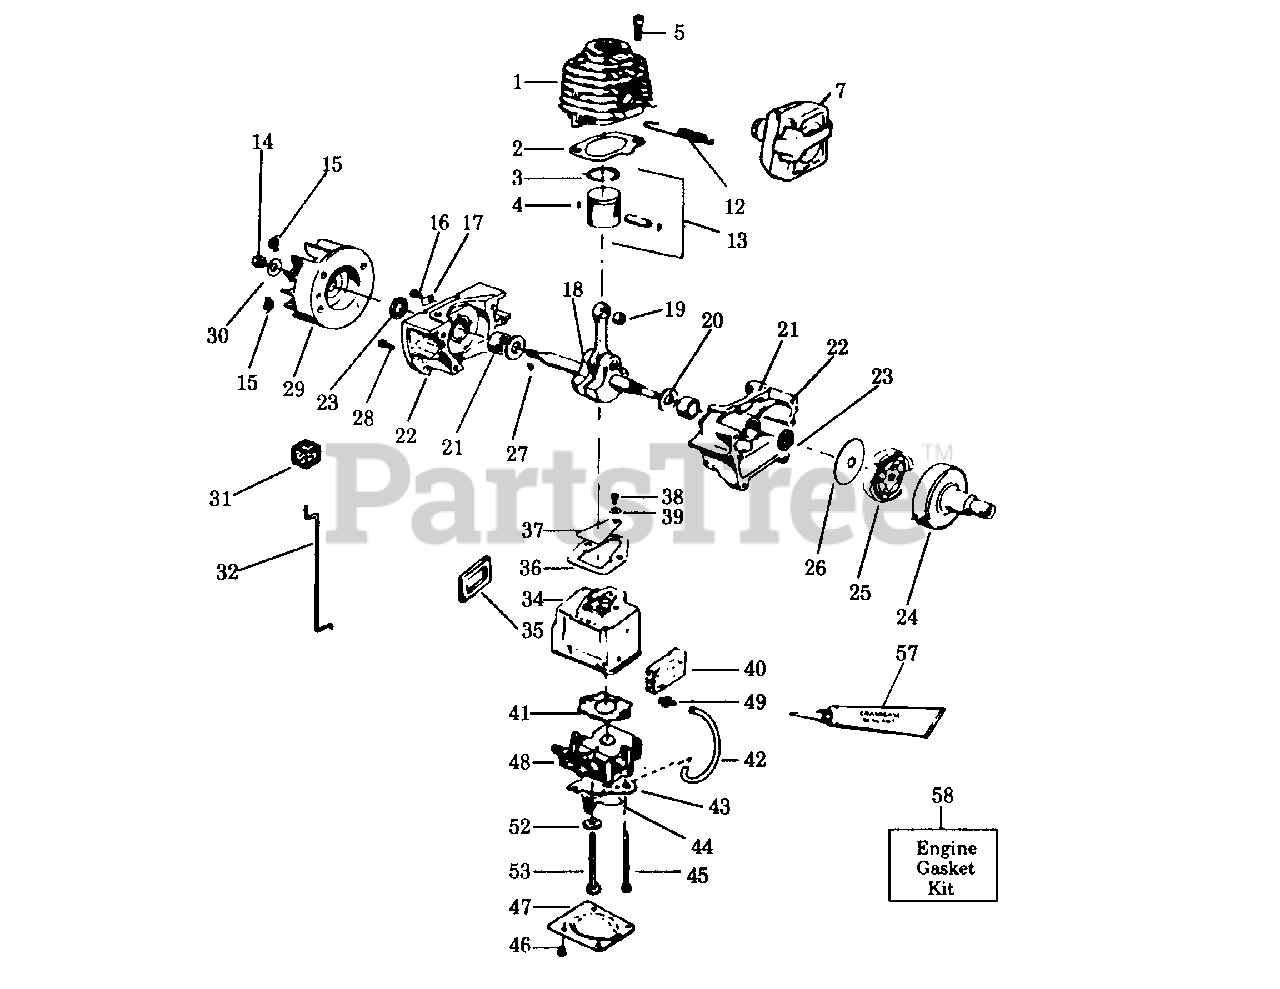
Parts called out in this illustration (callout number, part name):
1	Cylinder
2	Cylinder Gasket
3	Piston Ring
4	Wrist Pin Retainer
12	Muffler Attachment Spring
13	Piston Kit (Inc. #3,4 & Pin)
14	Flywheel Nut
15	Starter Dog Spring
17	Choke Wire Clamp
18	Crankshaft & Bearing Ass'y.
19	Wrist Pin Bearing
21	Crankshaft Bearing
22	Crankcase Ass'y. (Inc.21,23 & Qty. 1 of #26)
23	Crankcase Seal
24	Model XR-105
24	Model XR-125
25	Clutch Kit Ass'y.
26	Clutch Washer Kit
27	Flywheel Key
29	Flywheel Ass'y.
31	Choke Wire Boot
32	Choke Wire
34	Carburetor Hsg.
35	Carburetor Case Seal
37	Reed Valve
40	Carb. Case Seal
41	Carburetor Gasket
42	Line Kit
43	Choke Wire Guide Plate
44	Choke Shutter
47	Carb. Case Cover
48	Carburetor-WA-149
49	XR-105-T 1
49	XR-105-T 2 & XR-125-T 1
52	Wave Washer
57	Crankcase Sealant
58	Engine Gasket Kit
